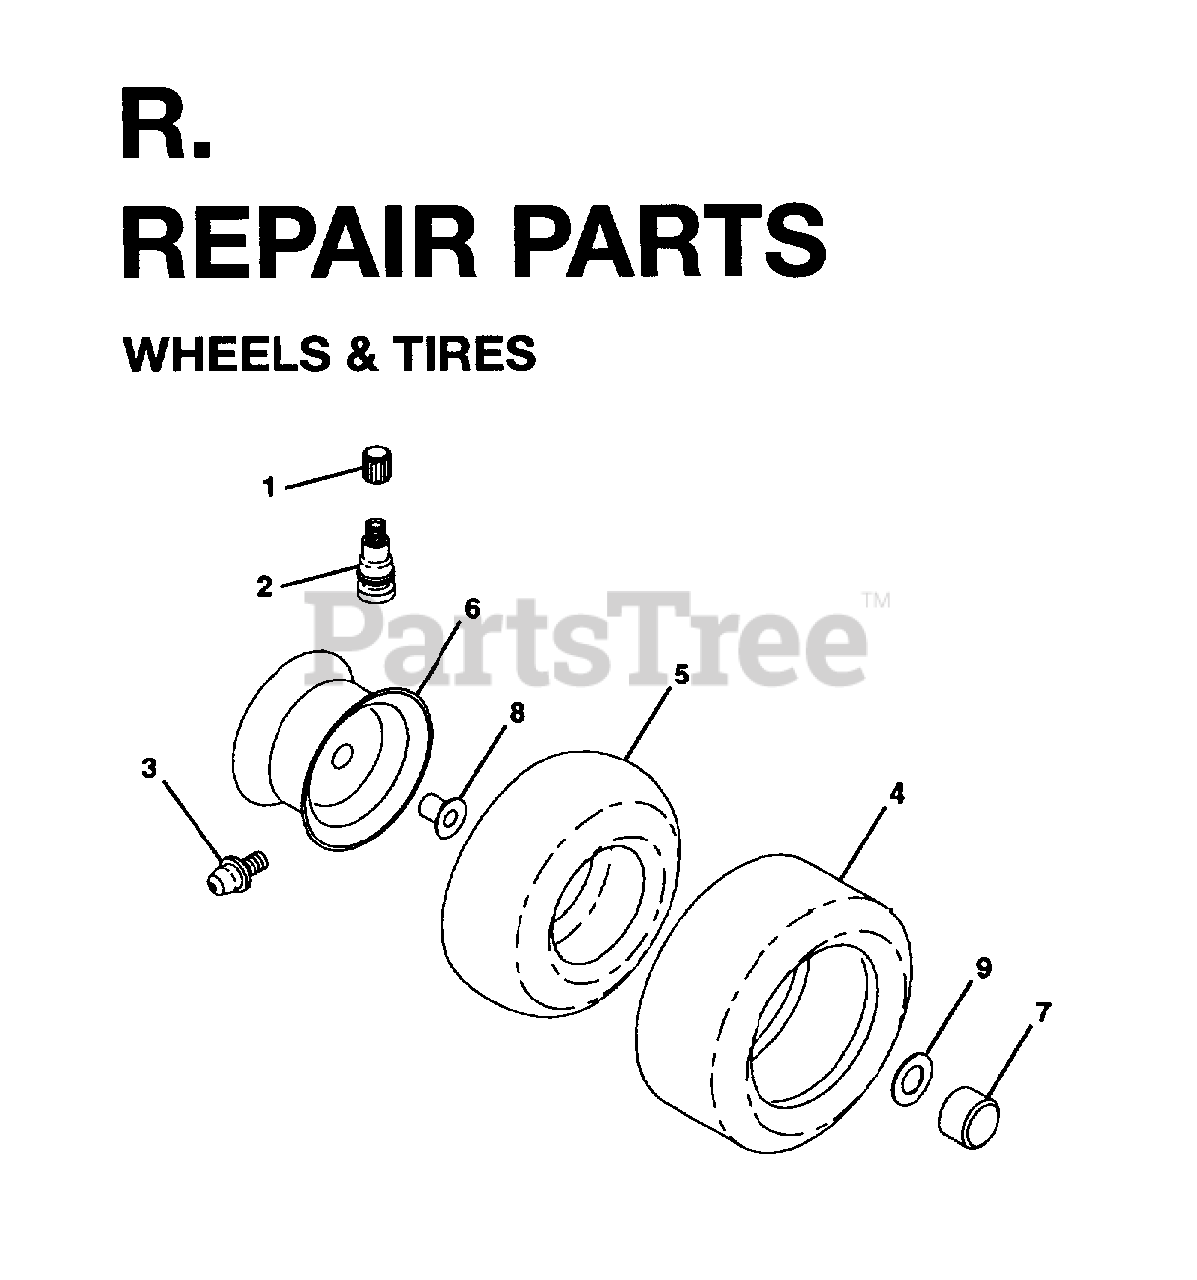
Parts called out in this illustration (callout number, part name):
1	VALVE CAP
2	VALVE STEM LT
3	FITTING LT
4	TIRE
4	REAR TIRE
5	TUBE.5.3/4.5/6
5	TUBE.16X6.5/7.5-8
6	RIM
6	RIM REAR 8"
7	CAP-HUB FRONT LT
8	BEARING T
